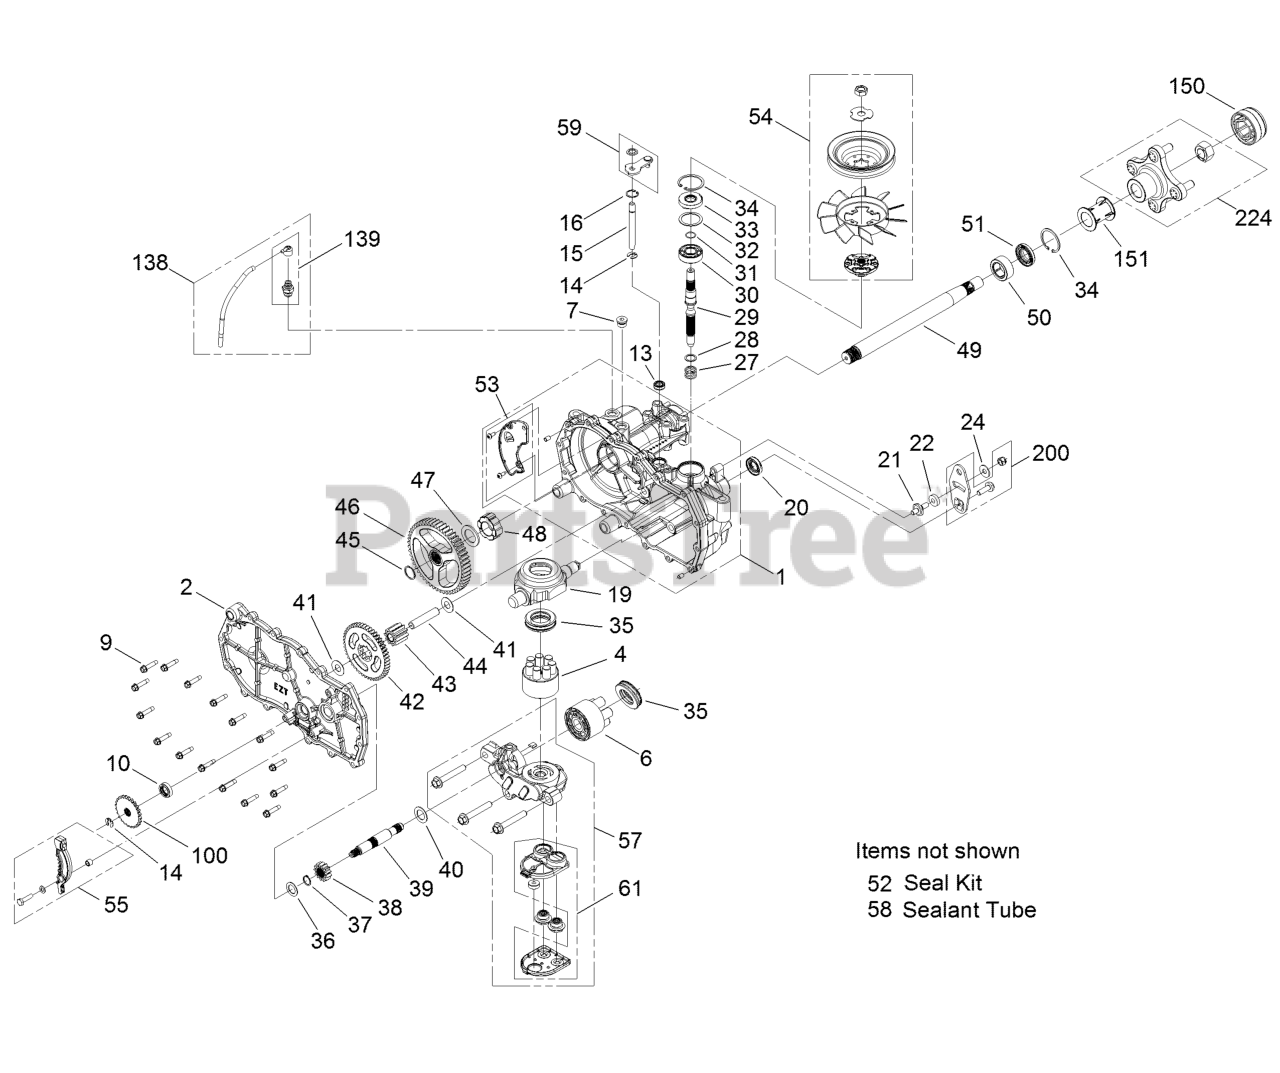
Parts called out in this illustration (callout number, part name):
1	MAIN HOUSING ASM
2	SIDE ASM
4	PUMP BLOCK ASM
6	CYLINDER BLOCK KIT
7	PLUG-THREAD, STRAIGHT
9	SCREW-HHF
10	SEAL-OIL
13	SEAL-LIP
14	RING-RETAINING, EXTERNAL
15	ROD-BYPASS
16	RING-RETAINING, INTERNAL
19	SWASHPLATE-TRUNNION
20	SEAL-LIP
22	PUCK-FRICTION
29	SHAFT-INPUT
30	BEARING-BALL
31	RING-RETAINING
33	SEAL-LIP
34	RING-RETAINING
35	BEARING-THRUST
36	WASHER-FLAT
37	RING-RETAINING
38	GEAR-PINNION, 13T
39	SHAFT-MOTOR
41	Washer
42	GEAR-10T/48T
43	GEAR-JACKSHAFT, 10T
44	PIN-JACKSHAFT
45	RING-SPIRAL, RETAINING
46	GEAR-52T, BULL
48	BEARING-SLEEVE
49	SHAFT-AXLE
50	BUSHING-AXLE
51	SEAL-LIP
53	EXPANSION PLATE KIT
54	Fan Pulley Kit
55	BRAKE ARM KIT
57	CENTER SECTION FILTER KIT
59	BYPASS ARM KIT
61	FILTER KIT
100	DISC-BRAKE, COG
138	BREATHER KIT
139	BREATHER ASM
150	COVER-NUT, AXLE
151	TUBE-AXLE
200	CONTROL ARM KIT
